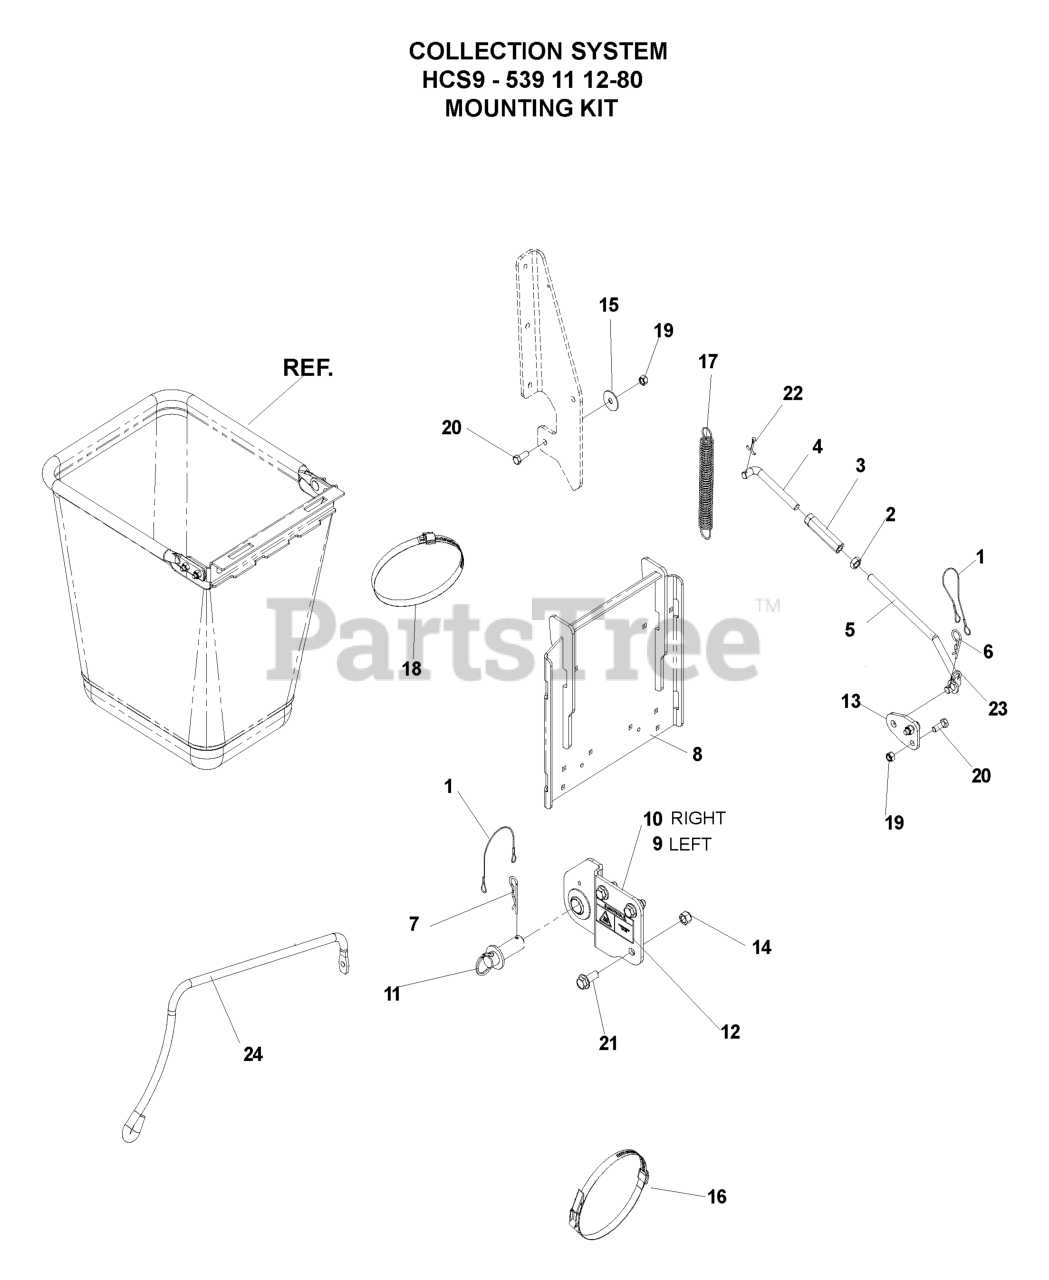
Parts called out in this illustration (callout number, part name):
2	NUT 1/2-20 HEX JAM ZD
3	TURNBUCKLE, 1/2
4	SUPPORT LINKAGE, LH
5	SUPPORT LINKAGE, MID
6	HAIRPIN #4
8	REAR GUARD WELDMENT
9	HITCH BRACKET WLD
10	HITCH BRACKET W/ DECAL MID
12	DECAL, HOT SURFACE
13	SUPPORT BRACKET
14	NUT 1/2-13 HEX NYLOC ZD
15	WASHER, FRICTION
16	OVER CTR BAND
18	HOSE CLAMP 4-1/8 TO 7"
19	NUT 3/8-16 NYLOC
20	HCS 3/8C X 1 1/2
21	HCS 1/2C X 1 1/4 SERRATED HEAD
22	COTTER PIN
24	HOSE SUPPORT
539111280	Mounting Kit Collection System
